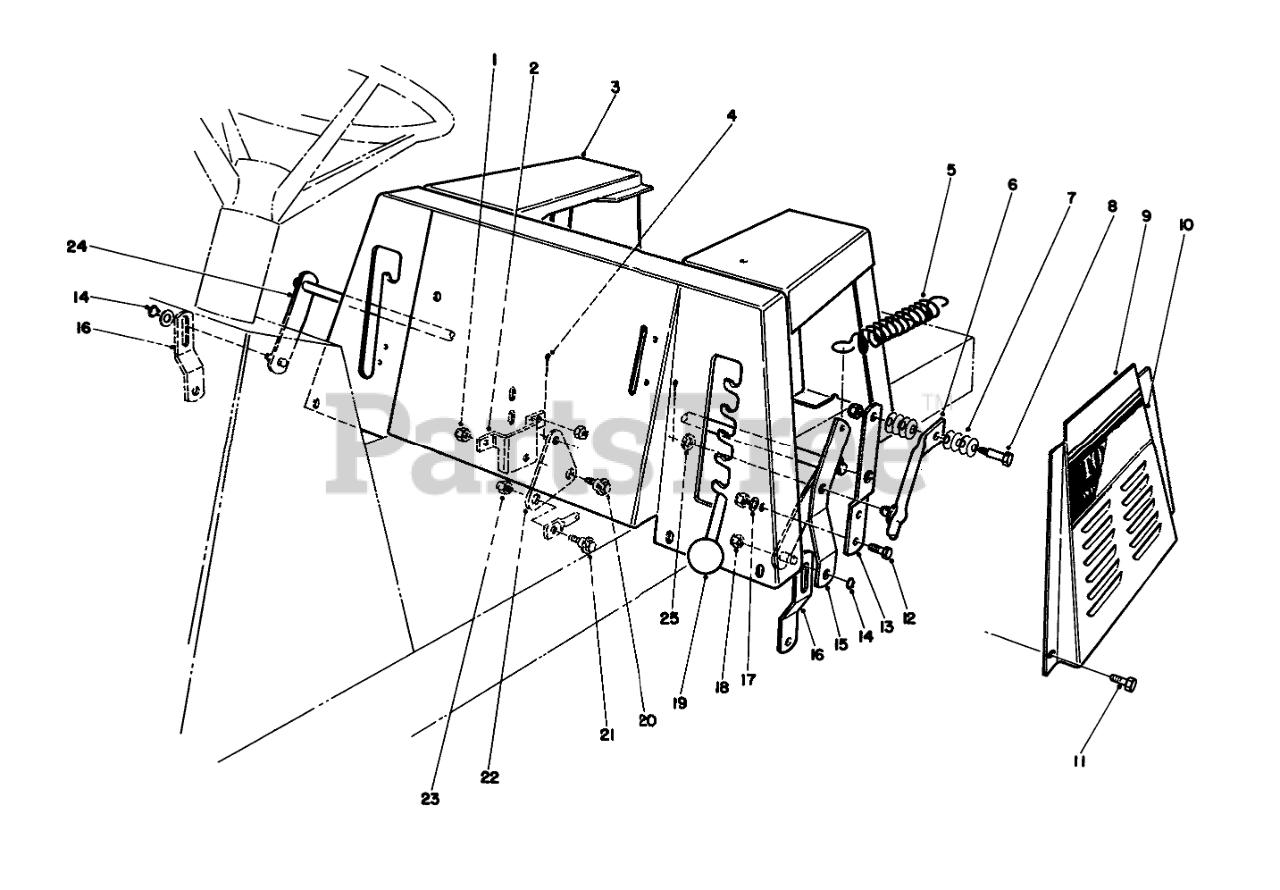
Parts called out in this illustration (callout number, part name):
1	NUT-LOCK, NI
2	BRKT-B.CRANK MTG
3	SEAT BODY WA R
4	PIN-COTTER
5	SPRING-EXTENSION
6	HOC LEVER WA B
7	WASHER-BELLEVILLE
8	BOLT-SHOULDER
9	L/H SEAT BASE PANELR
10	DECAL - LH TORO 12-32
11	SCREW-HH
12	SCREW-HH
13	Bracket
14	RING-RETAINING
15	Bracket-H.O.C., Engage
16	Link-Deck Suspension
17	WASHER-PLAIN
18	NUT-LOCK, NI
20	SCREW-SHOULDER
21	SCREW-SHOULDER
22	BELLCRANK
23	NUT-HEX
24	Arm
25	WASHER-FLAT
